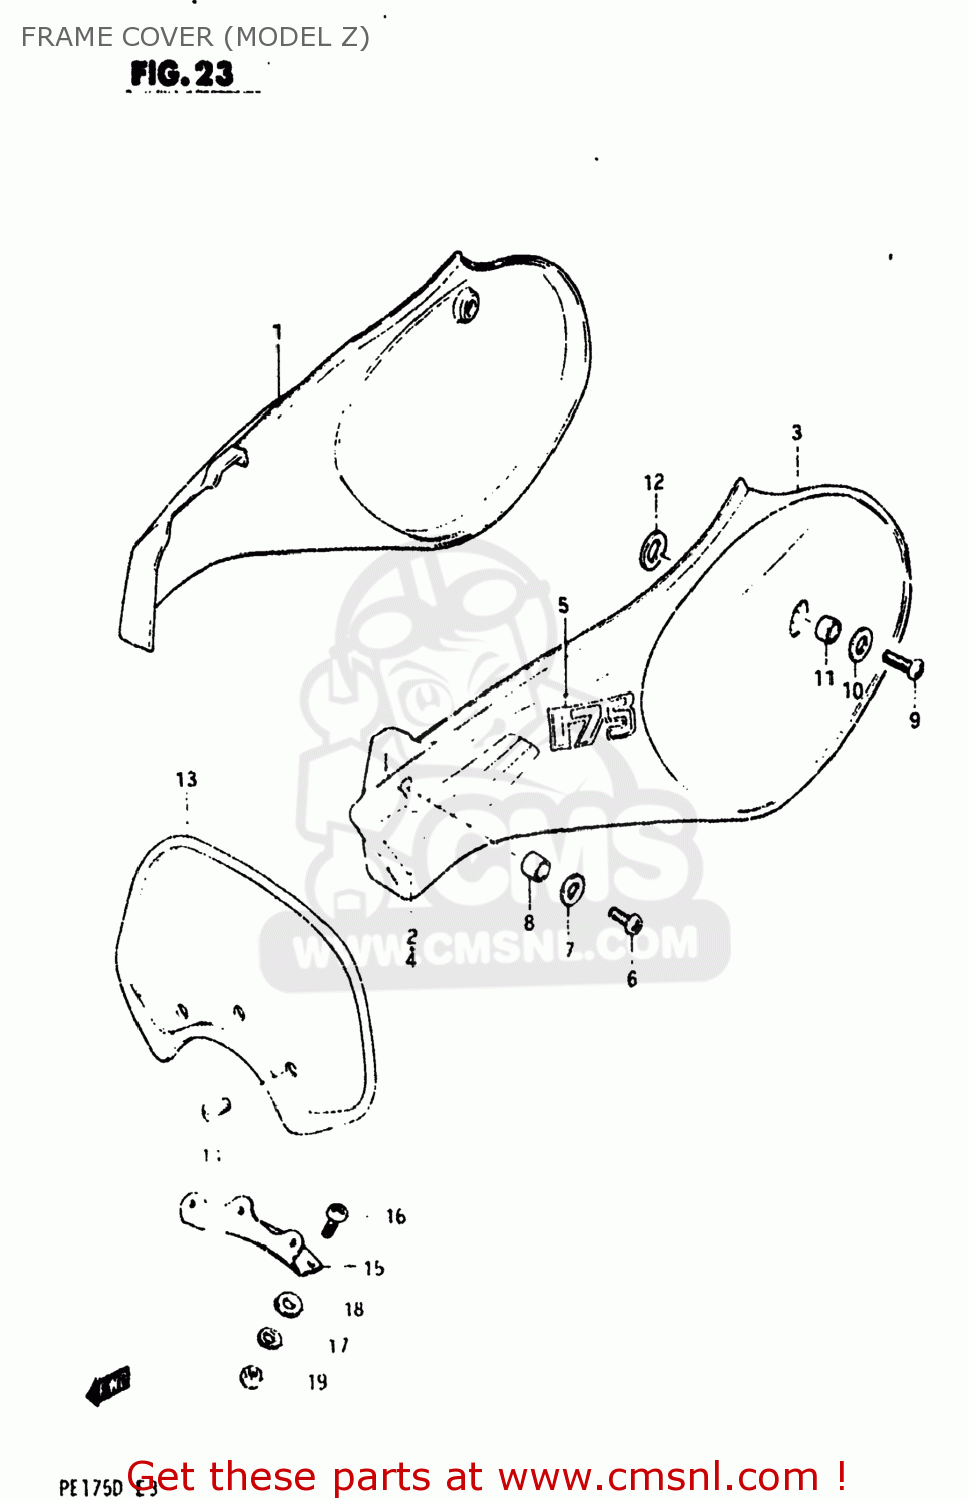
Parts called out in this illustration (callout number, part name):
1	COVER,FRAME,RIGHT
2	TAPE,FRAME COVER,RIGHT
3	COVER,FRAME,LEFT
4	TAPE,FRAME COVER,LEFT
5	EMBLEM
6	SCREW
7	WASHER
8	SPACER(6.3X9.3X16.5)
9	SCREW
10	WASHER
11	SPACER
12	GASKET
13	PLATE,FRONT NUMBER
14	SCREW
15	BRACKET FR NUM PLATE
16	SCREW
17	LOCK WASHER
18	WASHER
19	NUT
